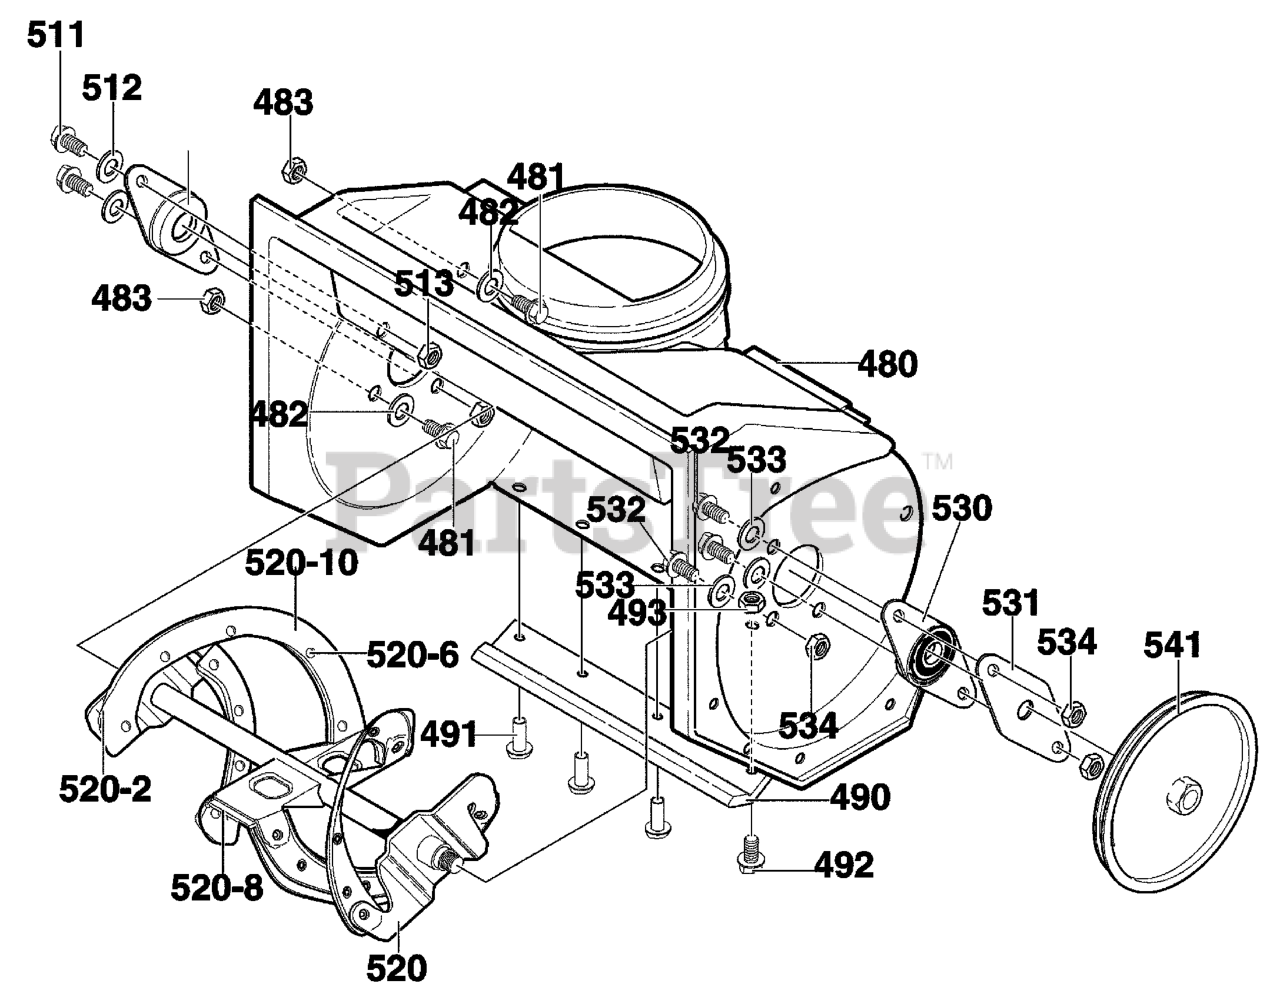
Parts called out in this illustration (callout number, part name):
480	HOUSING, ASSY
481	SCREW, 1/4-20X.75
482	WASHER, FLAT .281X.63X.065
483	NUT, 1/4-20 REGHEXCTRLK
490	BLADE, SCRAPER
491	RIVET, OVSET
492	SCREW, 1/4-20X.75
493	NUT, CNTRLK 1/4-20
510	BRNG,FL
511	SCREW, 1/4-20X1.00
512	WASHER, FLAT .281X.63X.065
513	NUT, CNTRLK 1/4-20
520	AUGER, ASSY
520-2	BLADE, AUGER
520-6	RIVET
520-8	BLADE, CENTER
520-10	AUGER & BLADE SUPPORT
530	BEARING & PLATE ASSY.
531	PLATE, RETAINER
532	SCREW, 1/4-20X.63
533	WASHER, FLAT .281X.63X.065
534	NUT, 1/4-20 REGHEXCTRLK
541	PULLEY, V3L 6.00
